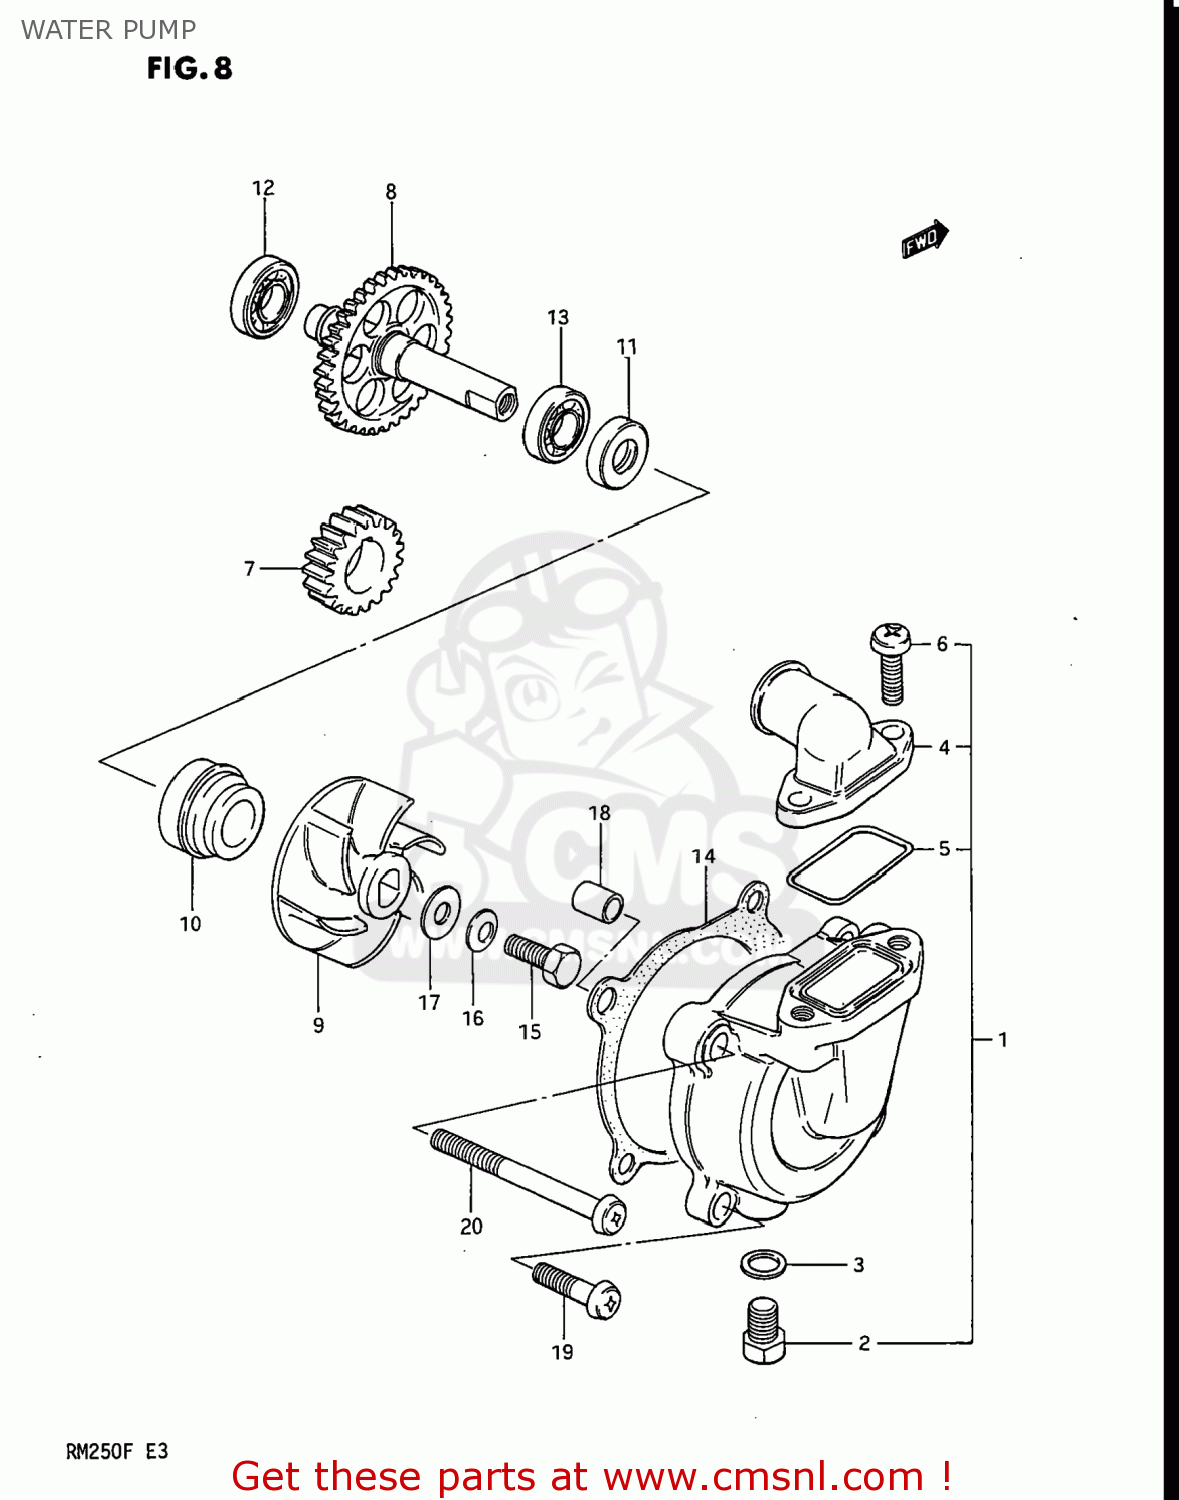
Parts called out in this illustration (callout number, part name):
1	CASE,WATER PUMP
2	BOLT,DRAIN
3	GASKET,DRAIN (NAS)
4	CONNECTOR
5	O RING,WATER PUMP CONNECTOR
6	SCREW
7	GEAR,WATER PUMP DRIVE
8	GEAR,WATER PUMP DRIVEN(NT:36)
9	IMPELLER,WATER PUMP
10	SEAL,WATER PUMP SHAFT
11	SEAL,OIL(10X21X5)
12	BEARING(10X22X6)
13	BEARING
14	GASKET,WATER PUMP CASE (MCA)
15	BOLT(6X13)
16	WASHER
17	GASKET (NAS)
18	PIN
19	SCREW
20	SCREW (6*60)
